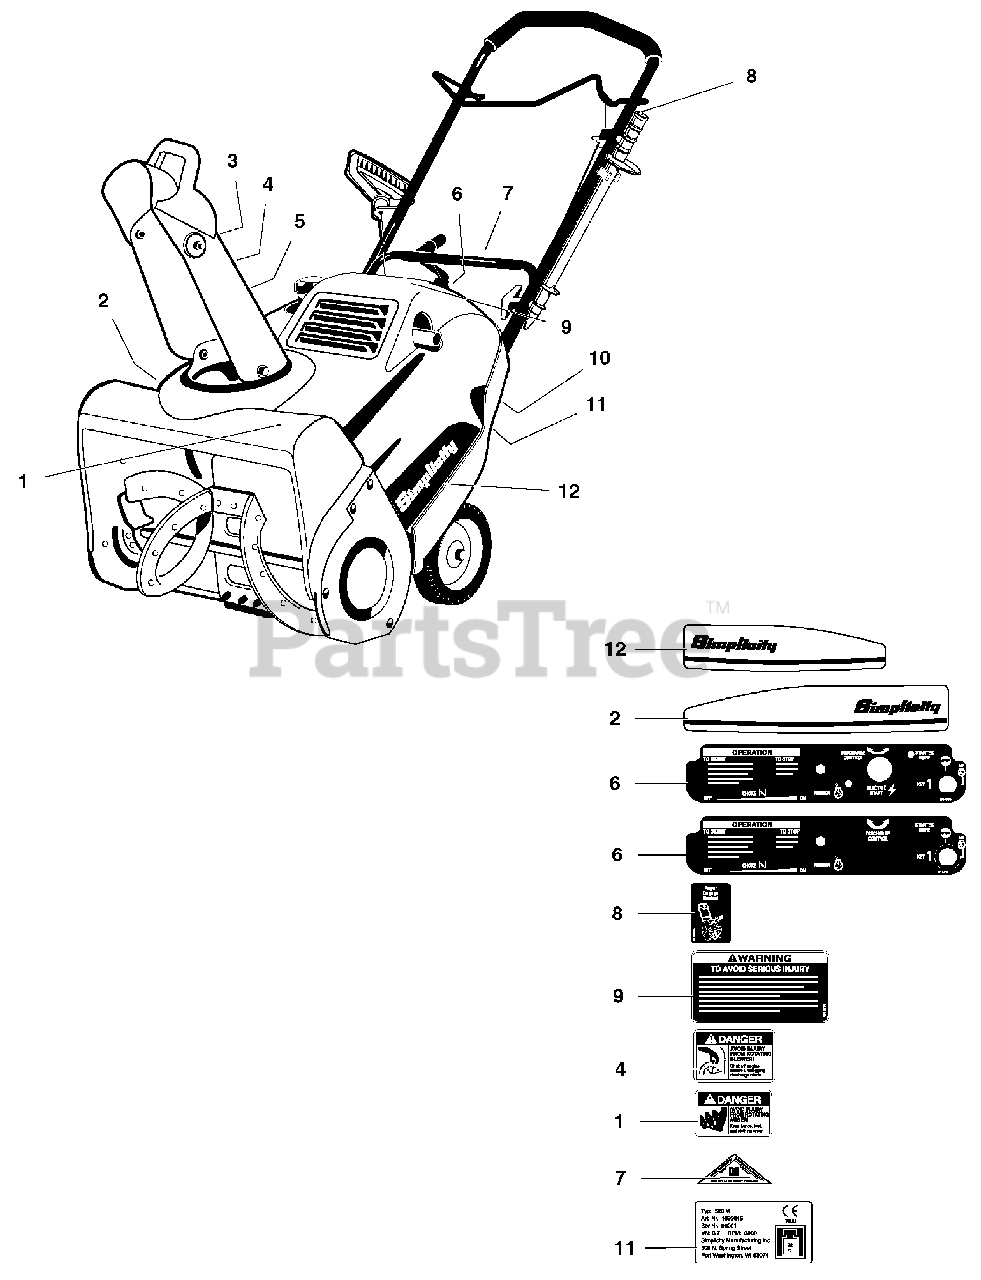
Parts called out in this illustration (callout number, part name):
1	DECAL, Danger, Auger
2	DECAL, Logo, R.H.
3	DECAL, Power-Mass (Export Models Only)
4	DECAL, Danger, Discharge Chute
5	DECAL, C.E. (Export Models Only)
6	DECAL, Console (Electric Start Models)
6	DECAL, Console (Manual Start Models)
7	DECAL, OPEI
8	DECAL, Auger Control
9	DECAL, Warning
10	DECAL, Compliance
11	SERIAL No.
12	DECAL, Logo, L.H.
